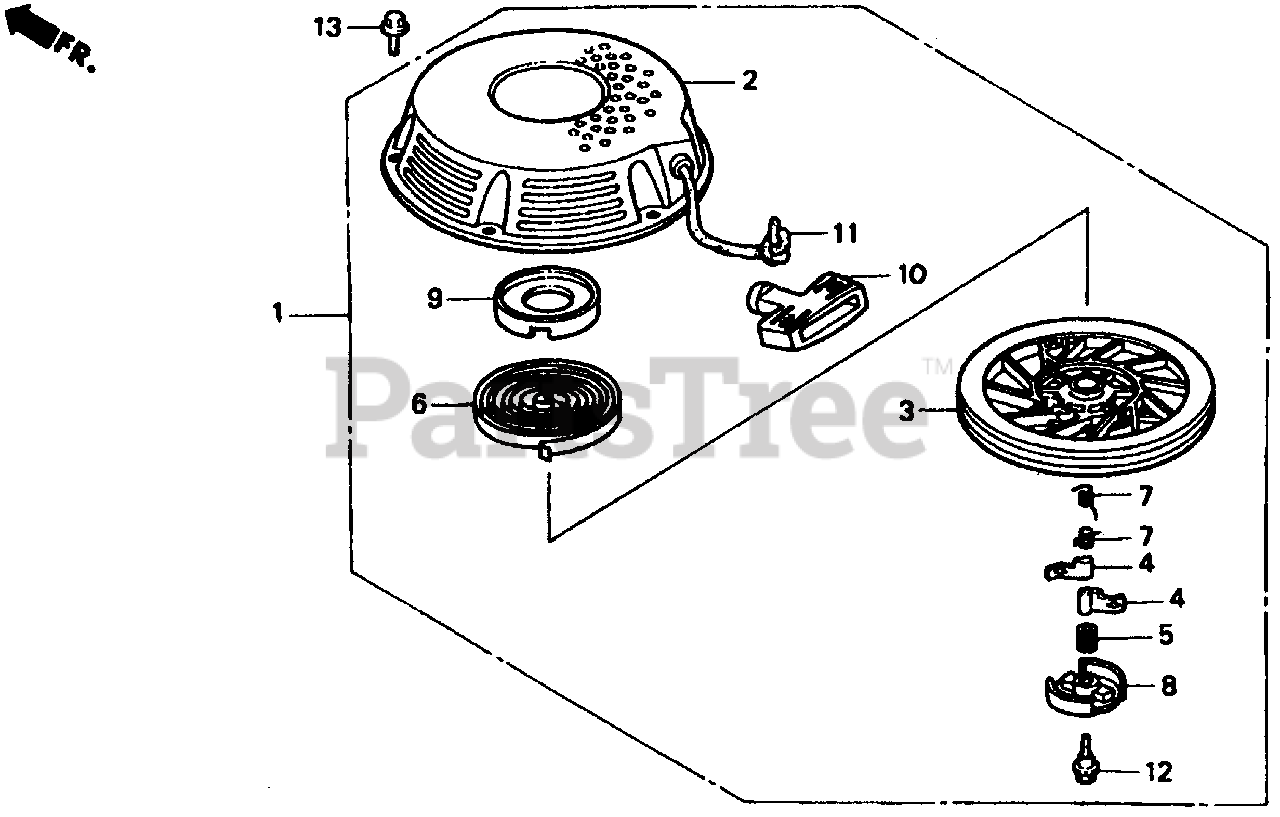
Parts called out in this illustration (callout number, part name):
1	STARTER ASSY., RECOIL *R8* (BRIGHT RED)
2	CASE, RECOIL STARTER *R8* (BRIGHT RED)
3	PULLEY, RECOIL STARTER
4	RATCHET, STARTER
5	SPRING, FRICTION
6	SPRING, STARTER RETURN
7	SPRING, RATCHET
8	RETAINER, SPRING
9	HOLDER, SPRING
10	GRIP, STARTER
11	ROPE, RECOIL STARTER
12	SCREW, CENTER
13	BOLT, FLANGE (6X10)
